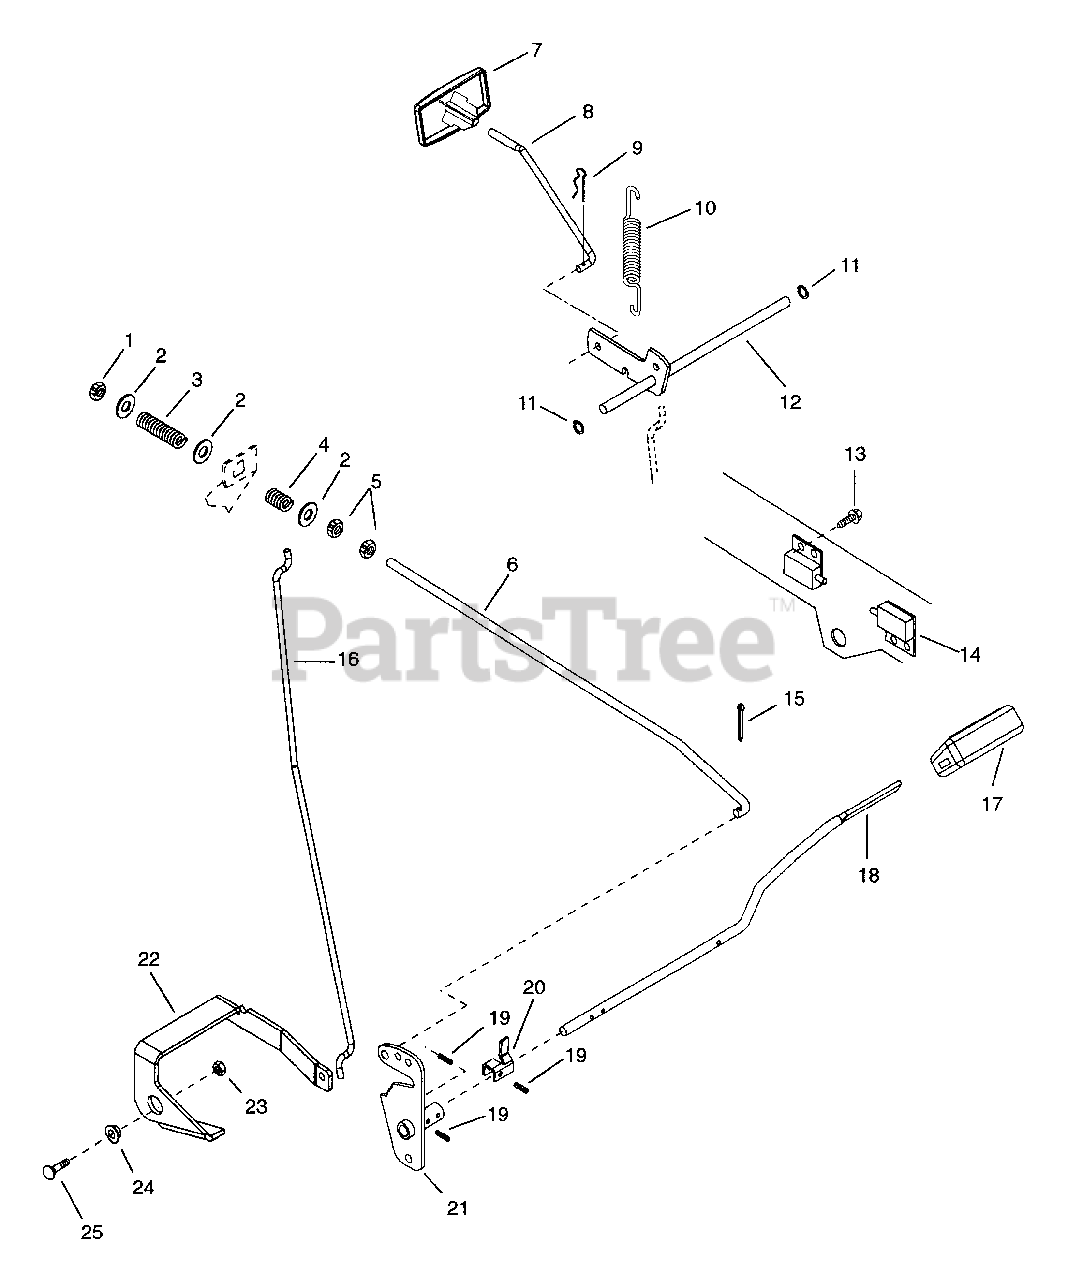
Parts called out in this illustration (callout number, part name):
1	NUT-LK-JAM-CTR .375-16 PL
2	WSHR-FL-STL.406X.812X.065PL
3	SG-COMP .048X.59X2.06 WLD9
4	SG-COMP .125X.78X1.00 YWZ
5	NUT-JAM .375-16 PL
6	ROD - BRAKE
7	KNOB- PARK BRAKE
8	ROD, PARKING BRAKE
9	PIN-HAIR INT .06X.18X.77
10	SG-TENS .051X.60X2.25 WLD 7.0
11	RG-RTNG-EXT .250X.010
12	BELLCRANK-PARKING BRAKE
13	SCR-TAP 12-24X.50 HWH PL TR
14	SWITCH- SINGLE POLE N.O.
15	PIN-COTR .09X.75 PL
16	ROD, PARKING BRAKE
17	COVER - PEDAL - BRAKE
18	PEDAL - BRAKE
19	PIN-GRV .188X1.25 TP A
20	LEVER - BRAKE SWITCH
21	ARM & HUB - BRAKE
22	LEVER, PARKING BRAKE
23	NUT-LK .312-18 GR A PL
24	BSHG, FLG .325X.499X.26X.88
25	BLT-RDHDSQNK.31-18X.75GR5SHTPL
